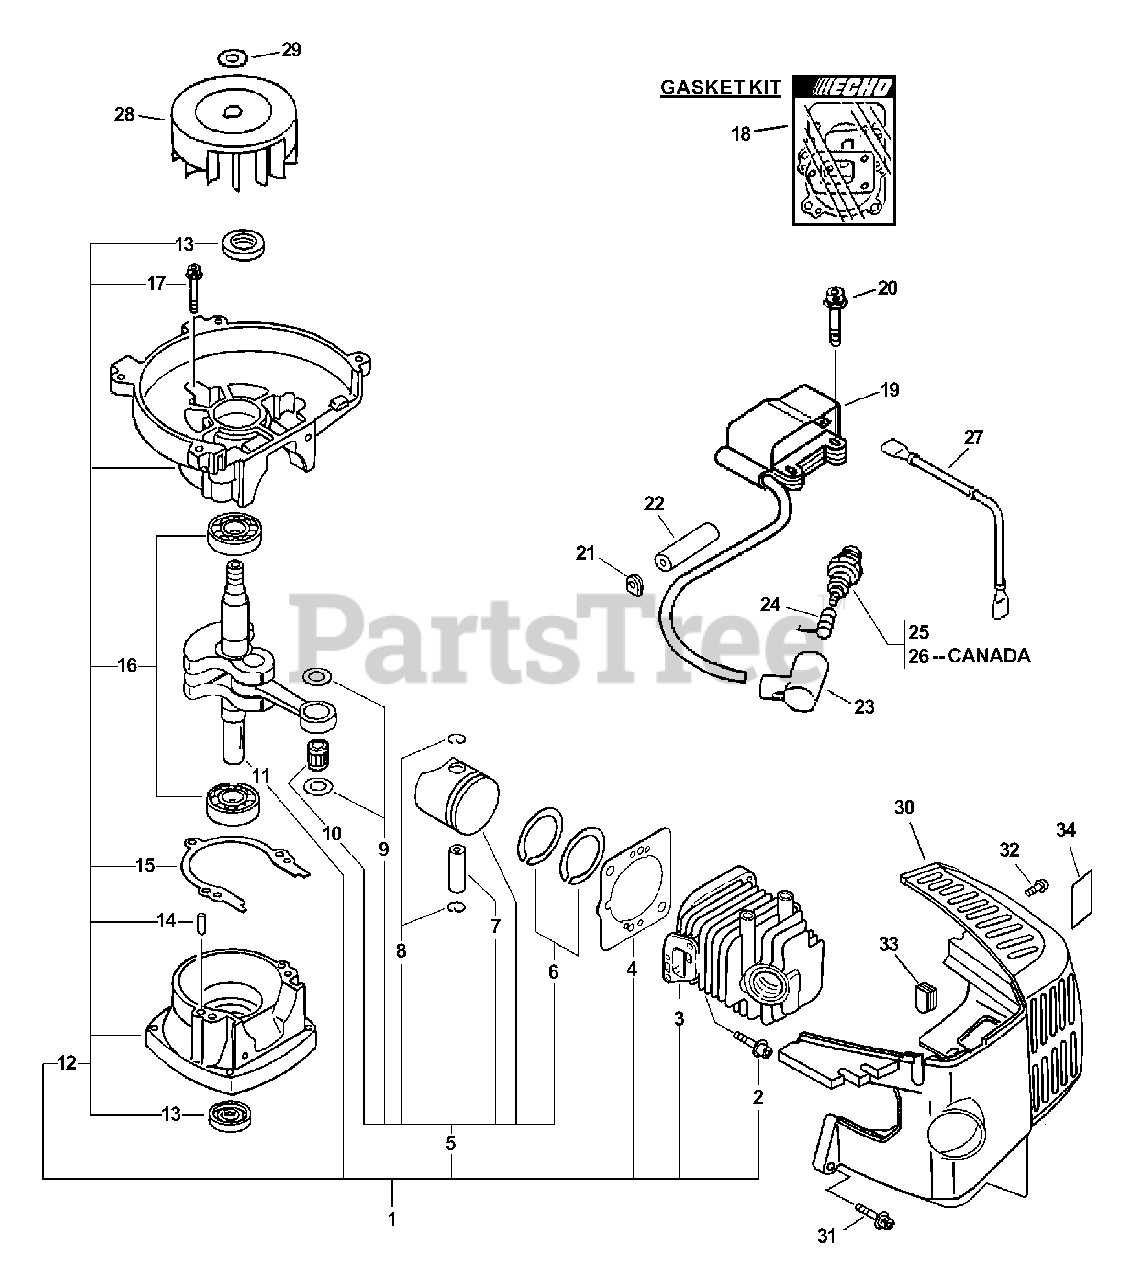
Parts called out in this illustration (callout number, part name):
1	SHORT BLOCK -- SB1068
2	SCREW - 5X22
3	CYLINDER
4	GASKET, CYLINDER
5	PISTON KIT
6	RING, PISTON
7	PIN, PISTON
8	RING, RETAINING
10	BEARING, NEEDLE - 8
11	CRANKSHAFT ASSY
12	CRANKCASE KIT
13	SEAL, OIL
14	PIN - LOCATING
15	GASKET, CRANKCASE
16	BEARING, BALL - 6201
17	SCREW - 5X28
18	GASKET KIT
19	COIL, IGNITION
20	SCREW - 4X20
22	TUBE, INSULATOR
23	CAP, SPARK PLUG
24	TERMINAL, SPARK PLUG CAP
25	SPARK PLUG -- BPM-8Y
26	SPARK PLUG -- BPMR-8Y
27	LEAD - IGNITION
28	FLYWHEEL
29	WASHER - 8
30	COVER, ENGINE
31	SCREW - 4X22
32	SCREW - 4X8
33	PLUG
34	LABEL - HOT SURFACE
